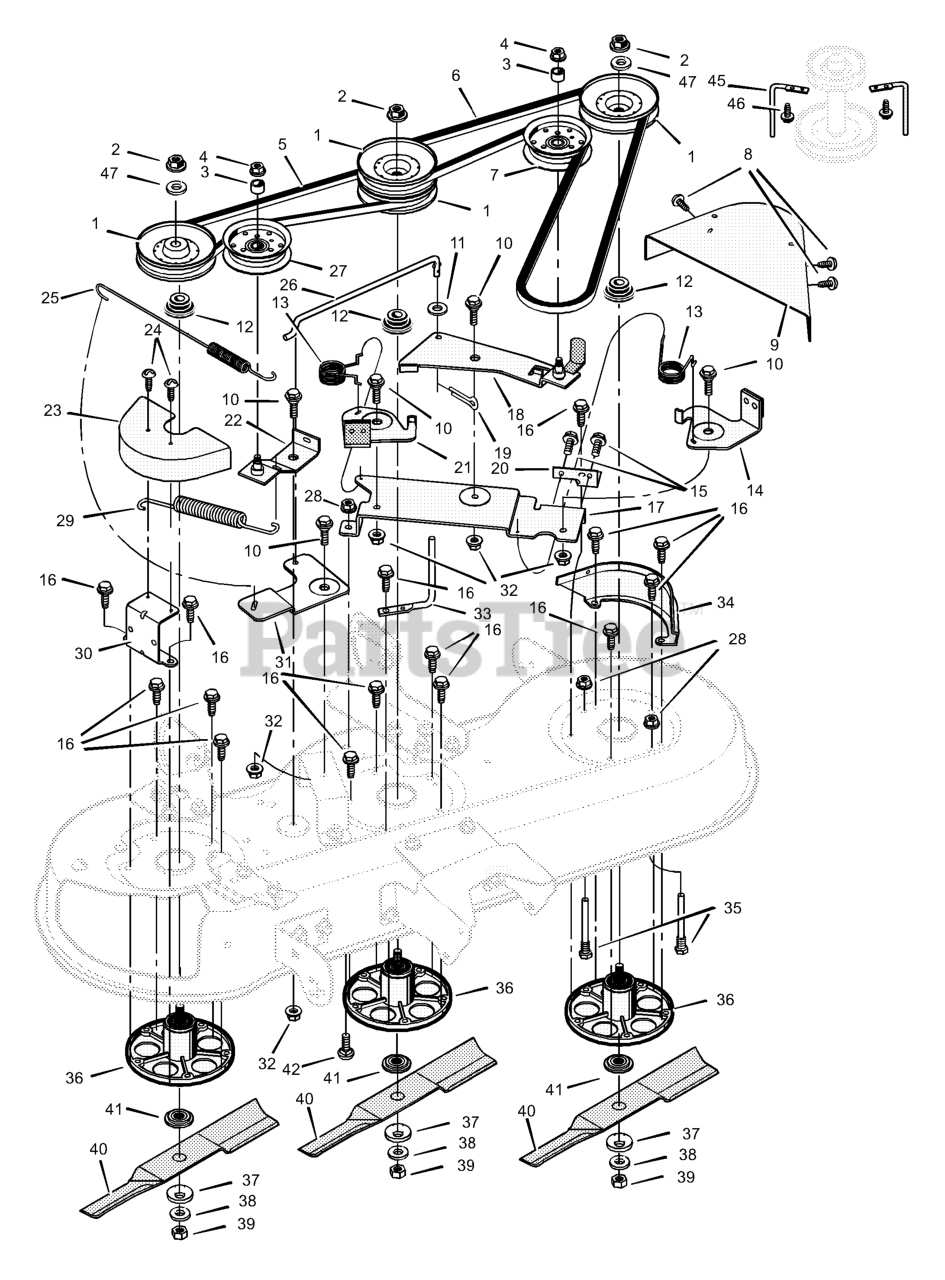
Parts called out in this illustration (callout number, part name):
1	Pulley
4	Nut, Centerlock
5	Belt, Secondary
6	Belt, Primary
7	V-Pulley
9	Cover, Left Pulley
10	Bolt, Shoulder
11	Washer
12	Spacer, Pulley
13	Spring, Torsion
14	Assembly, Left Brake
16	Screw
17	Plate, Brake Arm
18	Assembly, Idler Arm
19	Pin, Cotter
20	Bracket, Brake Plate Mount
21	Assembly, Center Brake
22	Assembly, Right Idler Arm
23	Cover, Right Pulley
24	Screw
25	Spring, Extension
26	Link, Bell Crank
27	Pulley, Backside
28	Nut, Flange
29	Spring, Extension
30	Cover, Bracket
31	Crank, Bell
32	Nut
33	Guide, Belt
34	Bracket, Pulley Cover
35	Guide, Belt
36	Assembly, Jackshaft Housing
37	Washer, Belleville
38	Washer
39	Nut
41	Adapter, Blade
42	Bolt, Carriage
45	Guide, Belt
46	Screw
47	Washer
